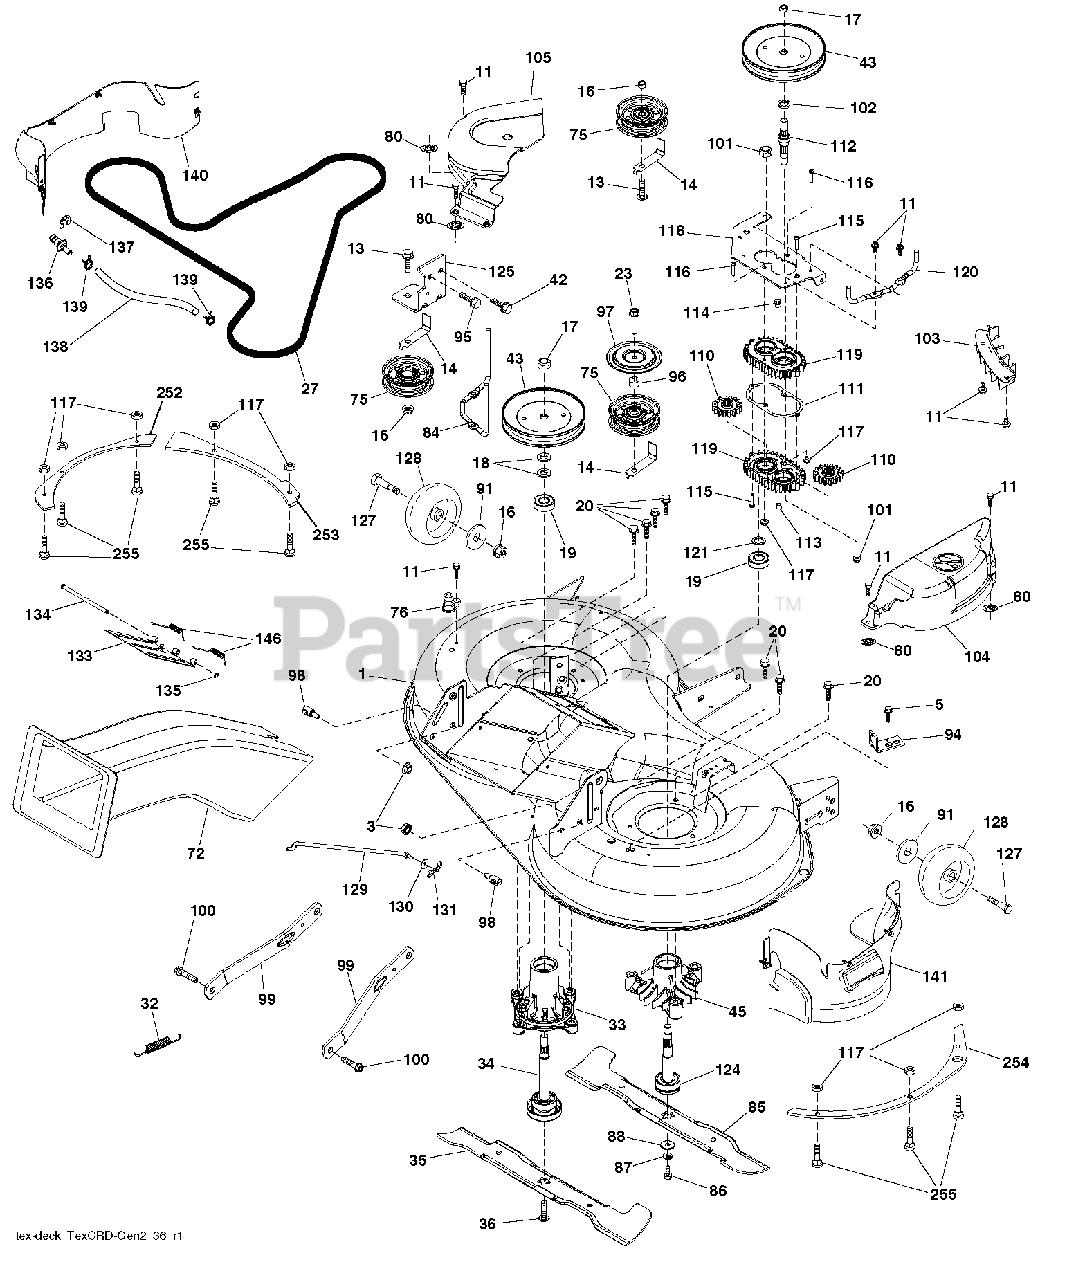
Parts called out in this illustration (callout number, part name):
1	DECK.SVC.WLDT.97EL.TCRD.EZ.498
3	NUT LOCK HEX FLANGE 5/16-18
5	BOLT.5/16HEX.WHS.HD
11	SCREW.1/4-20X5/8
13	BOLT.3/8-16X1.50
14	KEEPER, BELT IDLER
16	NUT LOCK FLG 3/8-16 UNC
17	NUT.FLANGE.LOCK.TOP
18	WASHER.SPACER.MANDREL
20	SCREW, WASHER HEAD
23	SCREW LT
27	BELT 97CM ELECTRIC
32	SPRING 107CM & 97CM ELECTRIC D
33	HOUSING.MANDREL.4PT.
34	SHAFT.ASM.MDRL.N/GREASE.38
35	BLADE.3N1.LH.CRD.97
36	BOLT.WASHER.ASM.7/16-2
42	SCREW
43	PULLEY.MANDREL.5.0.PD.38"
45	HOUSING.MANDREL.44/46" VENT
72	CHUTE.107/97.TEX.GEN2.TRIMMED
75	FLAT IDLER PULLEY
76	1/2" BARB.DECK.WASHOUT.PORT
80	PALNUT 1/4
84	BELT KEEPER.MANDREL.38"COATED
85	BLADE.3N1.RH.CRD.97
86	BOLT.3/8-24X1.25GR8. LHTHRD
87	LOCKWASHER
88	WASHER.BLADE
91	WASHER
94	BRKT.CLUTCH.CABLE
95	SCREW, 3/8-16X3/4
96	SPACER
97	PROTECTOR
98	STUD.FASTNER.W/ANTI-ROTATE
99	ARM.SUSPENSION.MOWER.R
100	BOLT.SHOULDER
101	NUT.CROWNLOCK.9/16 -18.UNC
102	SPACER BEARING
103	GUARD GUARD FRONT VENT
104	97.CRD.RH.MANDREL.COVER
105	MANDREL MANDREL COVER LH
110	GEAR GEAR OUTPUT
111	GASKET GASKET GEARCASE
112	SHAFT SHAFT. CRD GEARCASE ADAP
113	PLUG PLUG OIL
114	VALVE VALVE RELIEF
115	SCREW
116	BOLT.CARIGE.SS.1/4-20X1.75GR5
117	NUT T
118	ARM ARM CLUTCHING
119	GEARCASE GEARCASE SUBASM
120	BRACKET KEEPER BELT RH
121	WASHER WASHER
124	MANDREL SHAFT NON/GREASE
125	BRACKET BRACKET IDLER CHASSES
127	BOLT.SHOULDER.3/8-16X3-5/8.
128	WHEEL. GUAGE RALLY
129	ROD ROD. SWAY CRD GEN II
130	WASHER
131	PIN.COTTER.5/16.BOW TI
133	DOOR
134	PIN PIN.HINGE
135	E-RING.5/16"
136	PLUG WASHOUT PORT HOOKUP
138	HOSE.3/8ID.BULK.12"
139	HOSE.3/8.CLAMP (2 2)
140	GUARD
141	GUARD SUBASM.TEX CRD 97CM RH F
146	SPRING SPRING: EZ MULCH DOOR
252	PLATE 97 LEFT BOLT REINFORCING
253	PLATE 97 LH SIDE BOLT ON
254	PLATE 97 RH SIDE BOLT ON
255	RHSNB, 1/4-20 X 1, GR5
